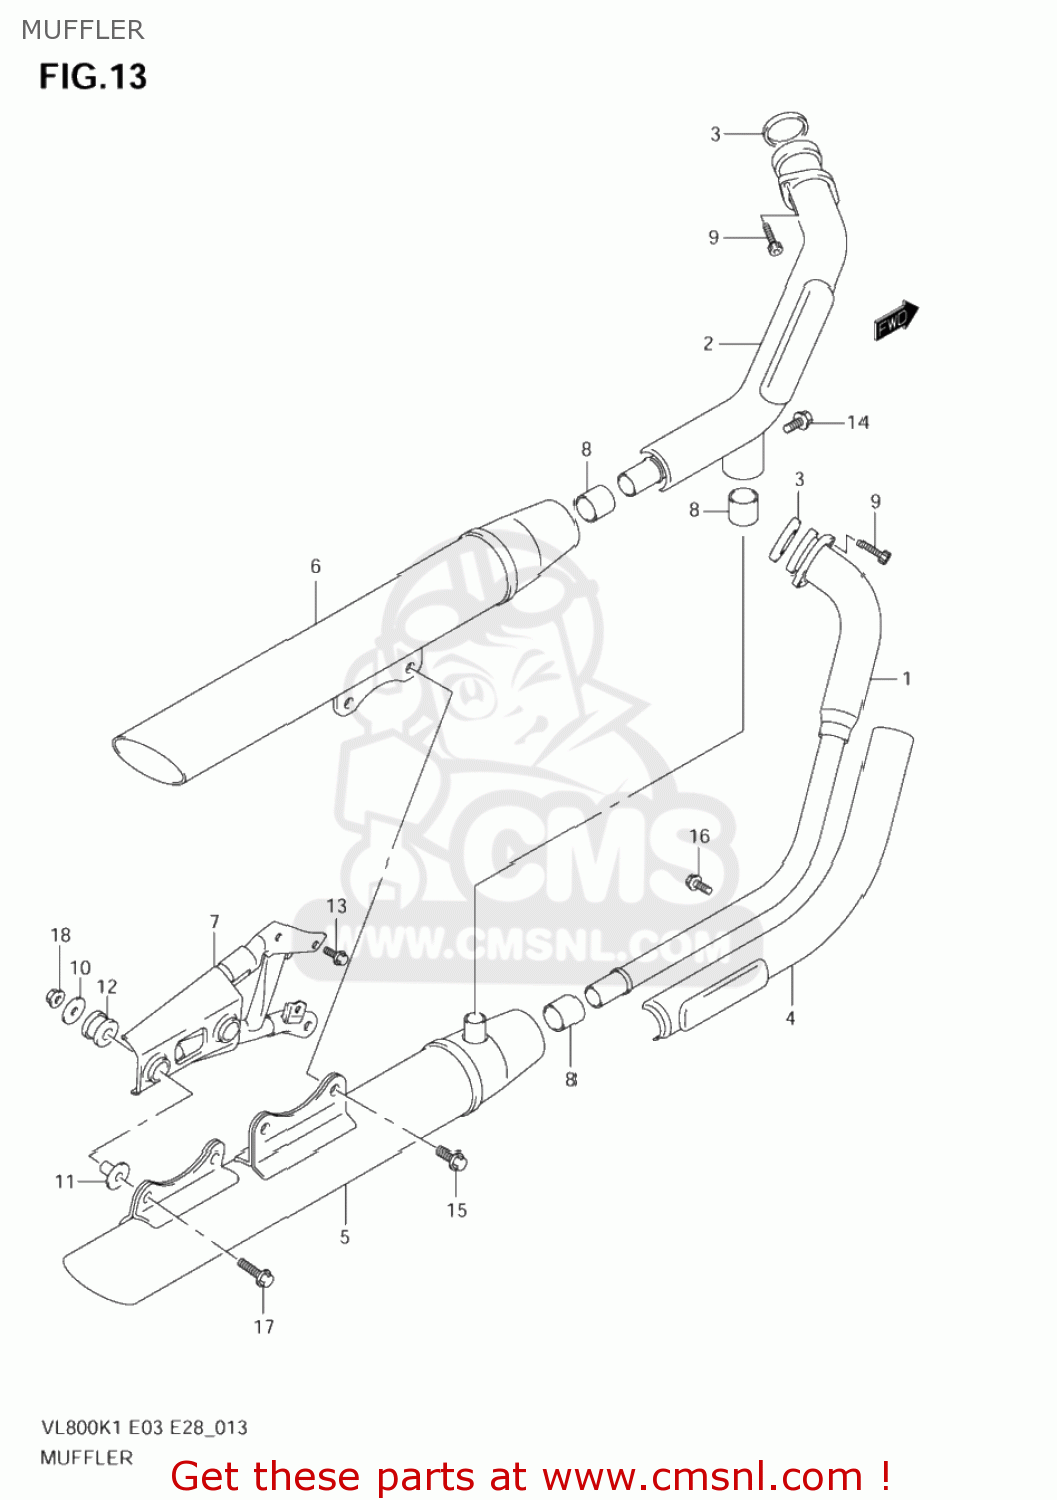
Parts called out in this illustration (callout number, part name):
1	PIPE,EXHAUST,F
2	PIPE,EXHAUST,R
3	GASKET,EXHAUST PIPE (NAS)
4	COVER,EXHAUST,
5	BODY,MUFFLER
6	BODY,MUFFLER
7	BRACKET,MUFFLER SUPPORT
8	CONNECTOR,MUFFLER
9	BOLT(8X25)
10	WASHER (8.5X33X1.6)
11	SPACER(8.6X12X27.1)
12	CUSHION
13	BOLT
14	BOLT
15	BOLT
16	BOLT MAGNETO S
17	BOLT(8X16)
18	NUT
